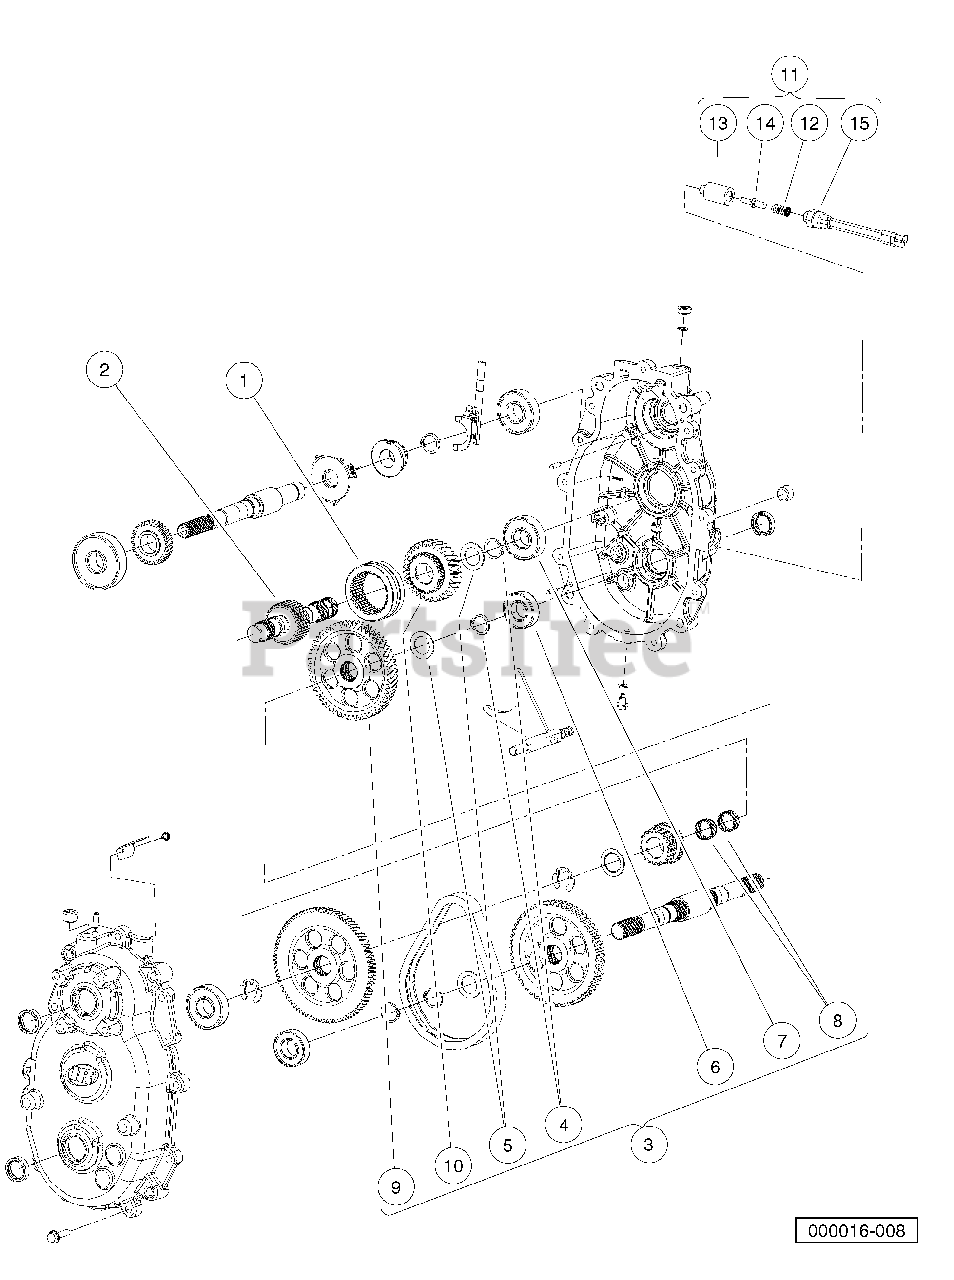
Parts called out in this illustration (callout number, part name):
1	Dog, Engagement
2	Shaft, Intermediate
3	Kit, Forward Gear Repair
4	Ring, Retaining, Basic External
5	Washer, Thrust, 1.007 X .062
6	Bearing, Ball
7	Bearing, Ball
8	Bearing, Needle
9	Gear, Helical 58-Tooth
10	Gear, Helical 34-Tooth
11	Kit, Neutral Switch Repair
12	Spring, .484 X .340 X 1.076
13	Guide, Detent Bullet
14	Bullet, Detent
15	Switch, Indicator, Pollak
